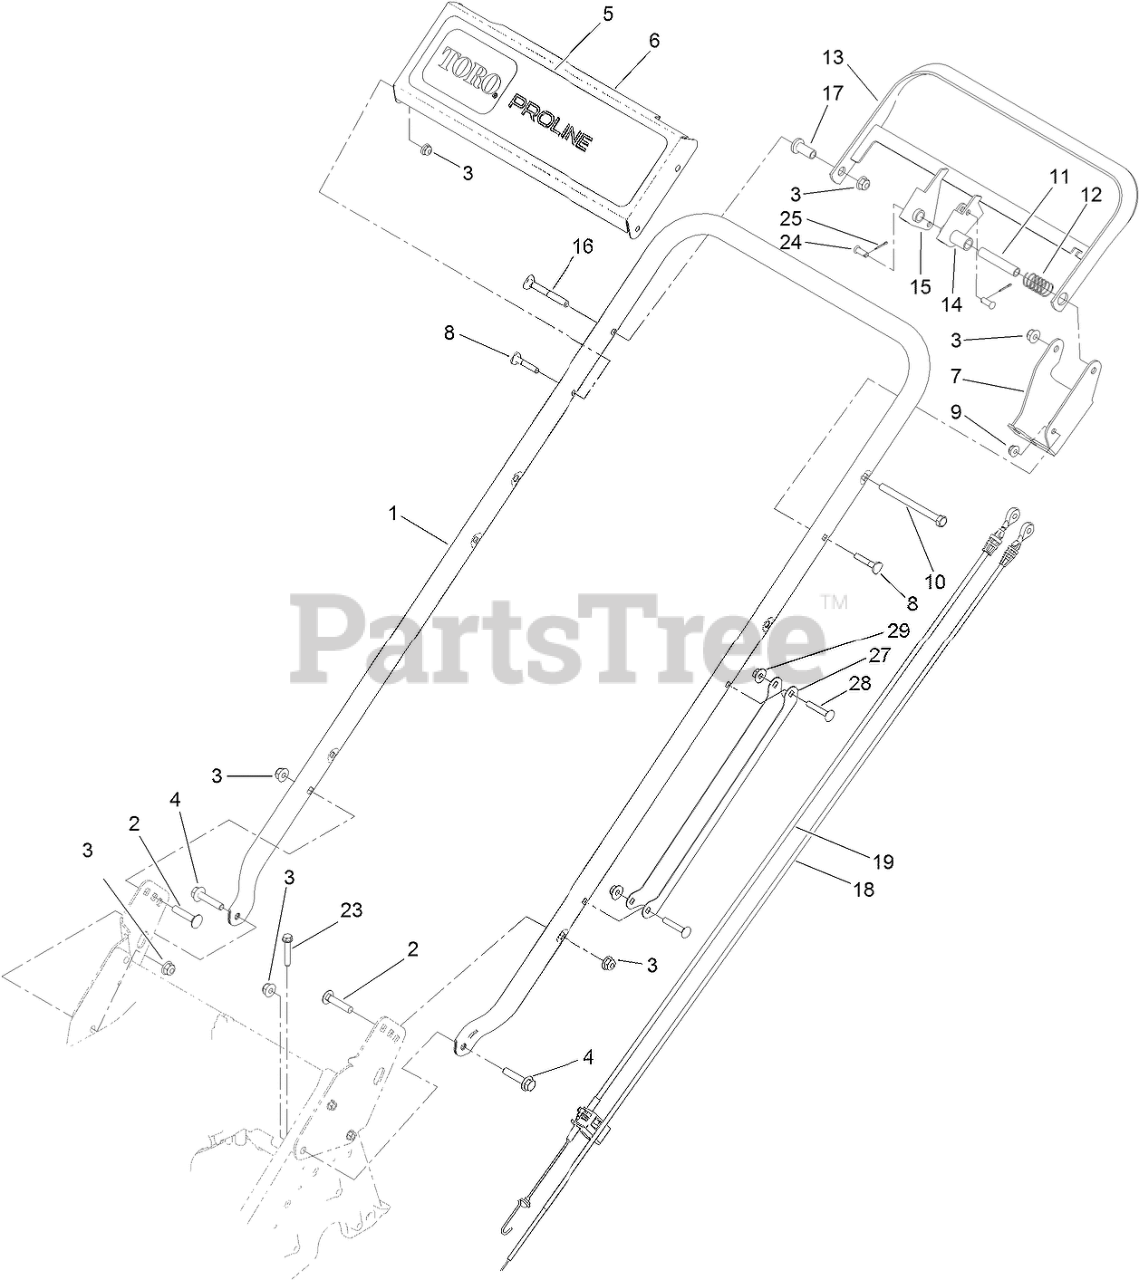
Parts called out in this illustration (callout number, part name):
1	HANDLE
2	BOLT-CARR
3	NUT-HF, NI
4	SCREW-HHF
5	DECAL-TORO, PROLINE
6	PANEL-CONTROL
7	BRACKET-CONTROL
8	SCREW-HANDLE
9	NUT-HF
10	SCREW-HH
11	SPACER
12	SPRING-CONTROL
13	BAR-CONTROL
14	LEVER-CONTROL
15	LEVER-TRACTION
16	SCREW-HANDLE
17	SPACER-FLANGE
18	CABLE-BBC
19	CABLE-TRACTION
23	SCREW-HWH
24	PIN-CABLE
25	PIN-COTTER
27	GUARD-CABLE, HANDLE
28	SCREW-CARR
29	NUT-HEX FLG
